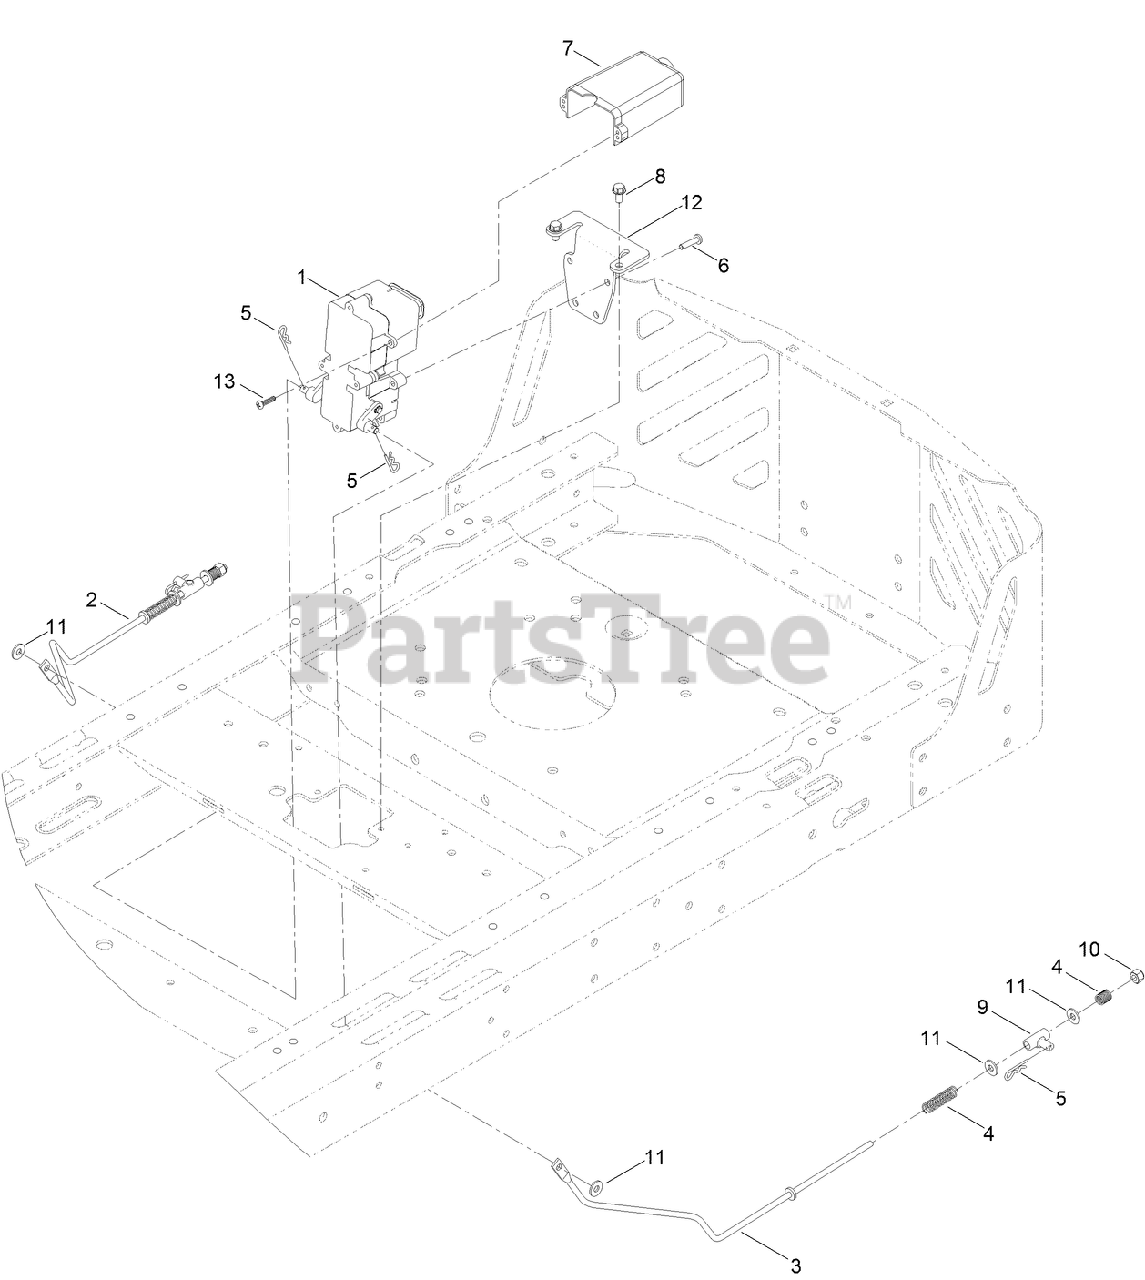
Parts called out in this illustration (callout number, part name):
2	ROD-BRAKE, RH
3	ROD-BRAKE, LH
4	SPRING-COMPRESSION
6	SCREW-PPH
8	SCREW-HWH
9	MOUNT-PIVOT
10	NUT-LOCK, NI
11	WASHER
12	BRACKET-MOUNT, BRAKE
13	SCREW-PPH
